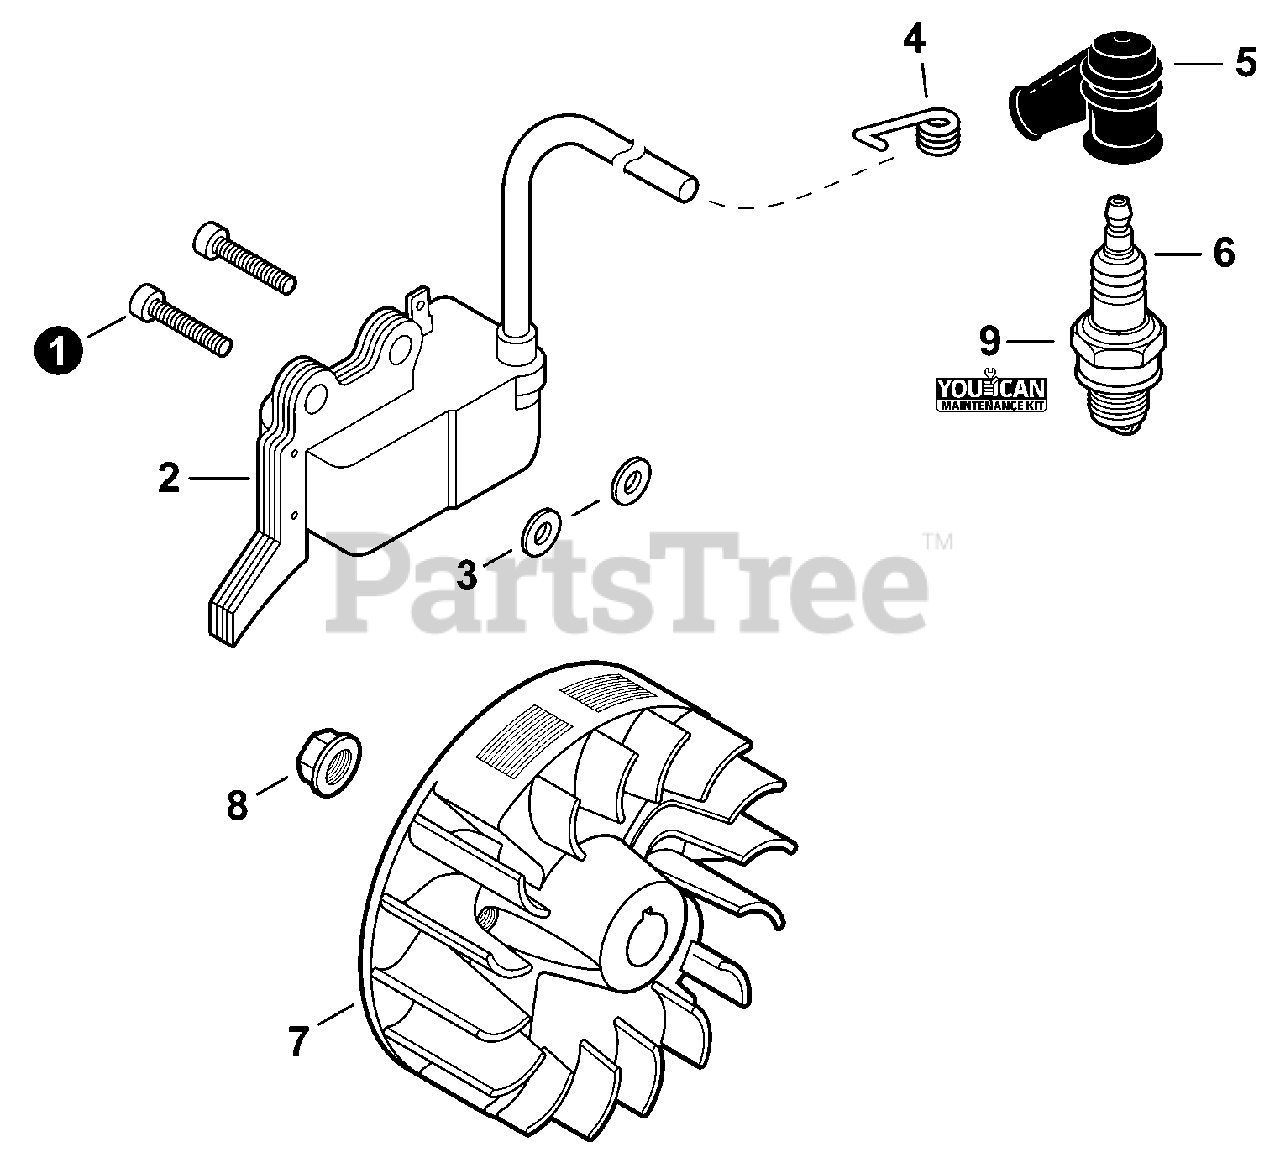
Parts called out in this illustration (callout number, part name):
1	BOLT, TORX 5×20
2	COIL, IGNITION
3	SPACER 5
4	TERMINAL, SPARK PLUG
5	CAP, SPARK PLUG
6	SPARK PLUG - BPMR8Y
7	FLYWHEEL
8	NUT, FLANGE M8
9	TUNE-UP KIT - YOUCAN™
